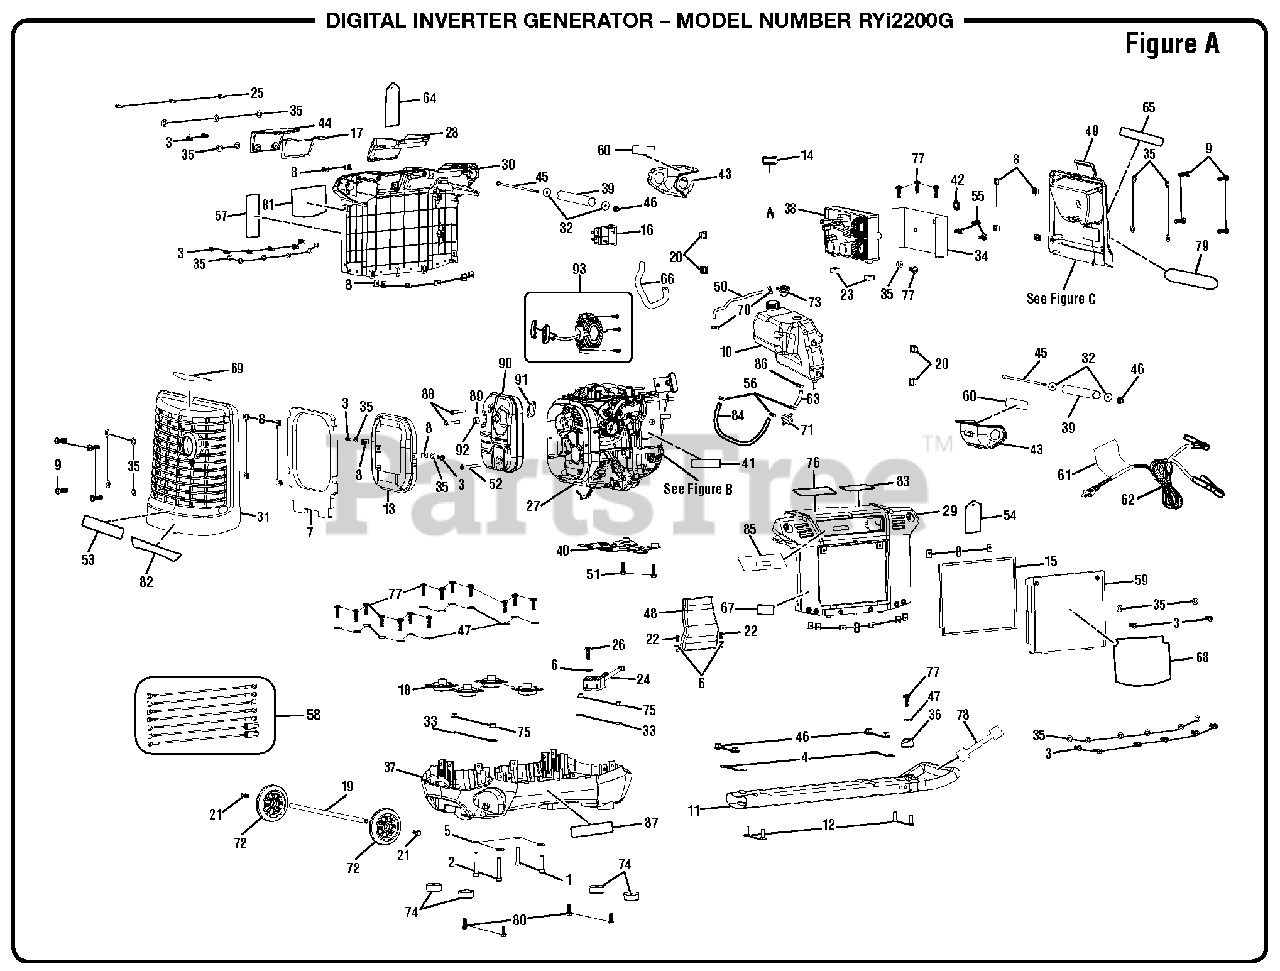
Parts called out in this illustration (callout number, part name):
1	Bolt (M8 x 35 mm, Hex Hd.)
2	Bolt (M8 x 50 mm, Hex Hd)
3	Screw (M5 x 12 mm, Phillips Pan Hd)
4	Washer (ID5.3 x OD15 x 1t)
5	Washer (ID8.3 x OD16 x 2t)
6	Washer (ID4.2 x OD10 x 1t )
7	Foam Pad (Isolator)
8	U-Clip (M5 x 0.8 in.)
9	Screw (M5 x 15 mm, Phillips Pan Hd.)
10	Fuel Tank
11	Handle Assembly
12	Screw (M5 x 0.8 in., Phillips Flat Hd.)
13	Muffler Noise Cover
14	Fuel Tank Cap
15	Seal (Maintenance Cover)
16	Carbon Canister
17	Spark Plug Cover (Foam)
18	Engine Bracket (Isolator)
19	Wheel Axle
20	Support (Fuel Tank)
21	Screw (M6 x 20 mm, Hex Button Hd.)
22	Screw (M3.5 x 9 mm, Phillips Flange Hd.)
23	Base Support
24	Bridge Rectifier
25	Screw (M5 x 30 mm, Phillips Button Hd.)
26	Screw (M4 x 10 mm, Phillips Pan Hd.)
27	Engine (105cc Top Sun)
28	Fuel Over spill Guard
29	Left Side Housing w/Labels
30	Right Side Housing w/Labels
31	Muffler Cover w/Labels
32	Washer (ID6.3 x OD25 x 1.5t)
33	Washer (ID6.3 x OD18 x 1.5t)
34	Air Guide Sheet
35	Washer (ID5.3 x OD10 x0.5t)
36	Handle Bumper
37	Base
38	Inverter Module
39	Handle (Upper)
40	Engine Bracket Assembly
41	Maintenance Label
42	Star Washer
43	Handle Cover
44	Access Cover (Spark Plug)
45	Bolt (M5 x 175 mm, Hex Hd.)
46	Flange Nut (M5 x 0.8 in.)
47	Washer (ID5.3 x OD10 x 1t)
48	Air Filter Duct
49	Control Panel Assembly
50	Air Hose (Fuel Tank)
51	Bolt (M8 x 30 mm, Hex Head)
52	Bolt (M6 x 65 mm, Flange Hex Hd.)
53	Combustion Label
54	Start Label Hang Tag
55	Bolt (M6 x 12 mm, Hex Hd.)
56	Clamp (D9.5 mm)
57	Danger Icon Label
58	Internal Wire Assembly
59	Maintenance Cover
60	Warning Transport w/Handle Label
61	Cord Label
62	DC Cable Assembly
63	Fuel Hose (50 mm)
64	Danger Hangtag
65	Logo Label (Small)
66	Air Hose (Carbon Canister To Air Box)
67	Check Oil Label
68	Logo Label (Large)
69	Hot Surface Label
70	Clamp (7 mm)
71	Fuel Filter (1/4 in.)
73	Rollover Vent
74	Rubber Foot w/Metal Insert
75	Nut (M6 x 1 mm )
76	CPSC Label
77	Screw (M4.2 x 12mm, Phillips Button Hd.)
78	Handle Release Label
79	Ground Warning Label
80	Bolt (M6 x 16 mm, Hex Hd.)
81	Performance Label
82	Fire Distance Label
83	E85 Label
84	Fuel Hose (Fuel Tank To Fuel Pump)
85	Quick Start Label
86	Clamp (10 mm)
87	Data Label
88	Bolt (M6 x 45 mm, Flange Hex Hd.)
89	Screw (M4.2 x 8 mm, Pan Hd.)
91	Exhaust Pipe Gasket
92	Spark Arrestor
93	Recoil Starter Assembly
